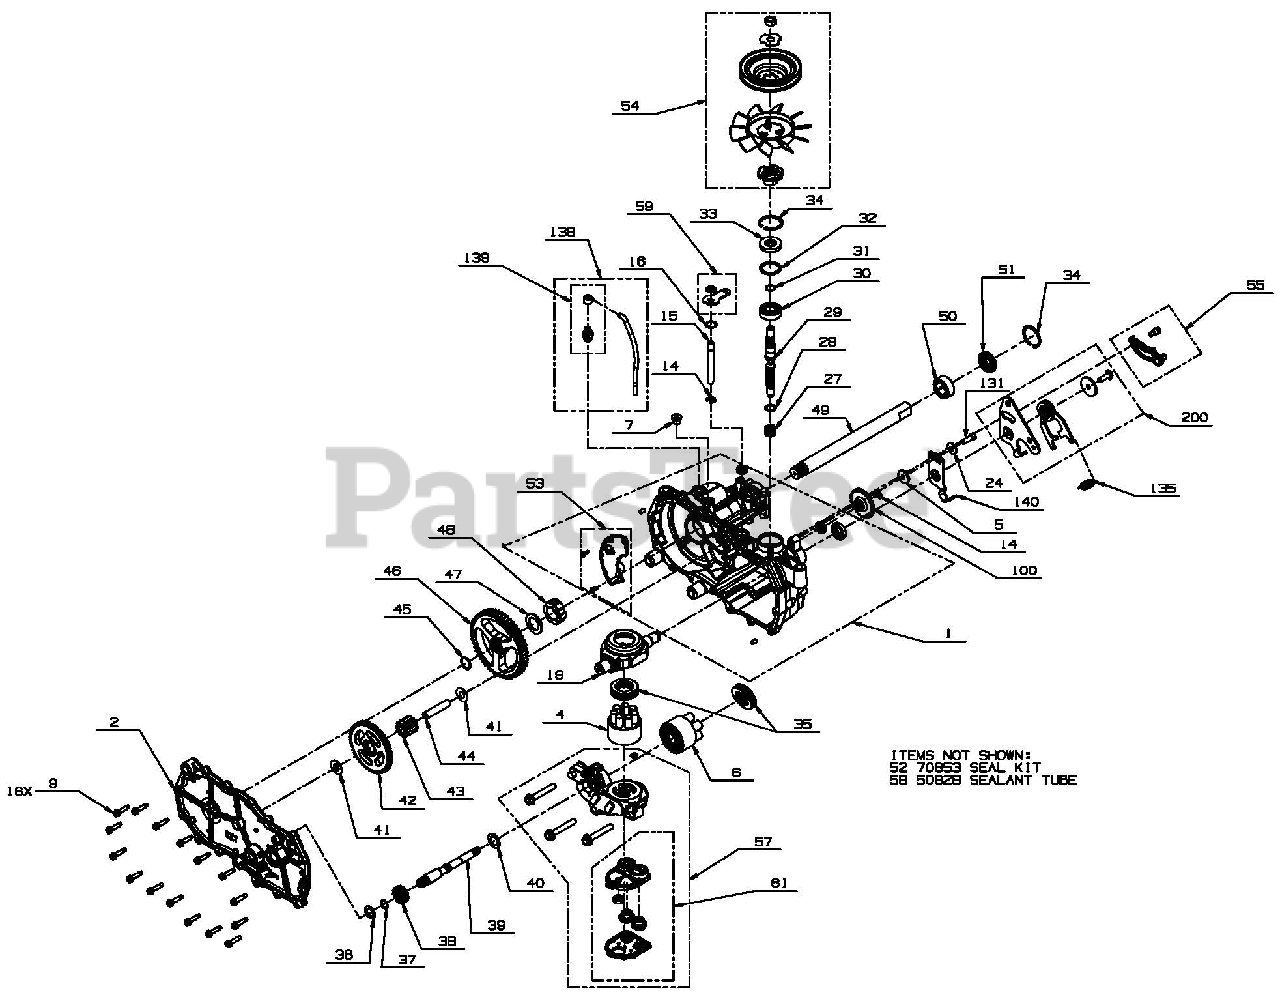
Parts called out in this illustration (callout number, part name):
4	ASSEMBLY, PISTON BLOCK - 7P IOCC
5	SPACER, .320 X 1.005 X .179
6	ASSEMBLY, PISTON BLOCK - 5P IOCC
9	HFHCS 1/4-20 X I.I25
14	RING, RETAINING .375 EXT
15	ROD, BYPASS
16	RING, RETAINING .750 INT
19	SWASHPLATE, TRUNNION, MACHINED
24	WASHER, .34 X .88 X .06
27	SPRING, HELICAL COMPRESSION
28	WASHER, .591 X .787 X .040
29	SHAFT, INPUT
30	BEARING, BALL 17MM ID X 40MM OD X 12
31	RING, RETAINING WIRE .561 ID
32	SPACER
33	SEAL, LIP 1 7 X 40 X 7
34	RING, RETAINING
35	BEARING, THRUST 30 X 52 X 13
36	WASHER, 5/8 X I.0 X .05
37	RING, RETAINING
38	GEAR, PINION 13T
39	SHAFT, MOTOR
40	WASHER, .7I X I.I6 X .04
41	WASHER, HT .5 ID X I.0 OD X .032
42	GEAR, 10T/48T
43	GEAR, 10T JACKSHAFT
44	PIN, JACKSHAFT
52	KIT, SEAL
53	PLATE EXPANSION, LH
54	KIT, FAN-PULLEY
55	KIT, BRAKE ARM, THROUGH HOLE
58	SEALANT TUBE
59	KIT, BYPASS ARM W/ THRU HOLE
61	KIT, FILTER
100	DISC, COG BRAKE
131	KIT, RTN SCREWS
135	SPRING, EXTENSION CLEAR ZINC
140	ARM, NEUTRAL LEFT
